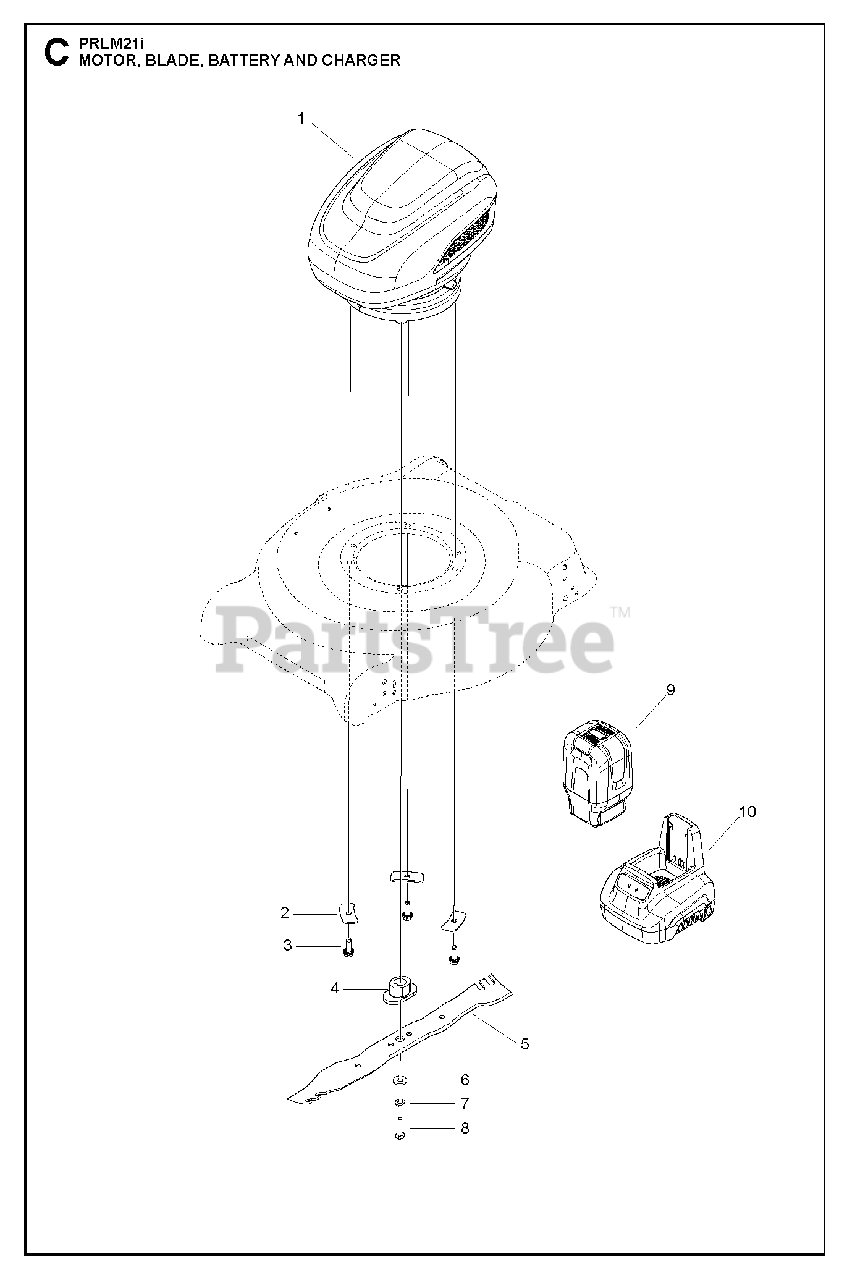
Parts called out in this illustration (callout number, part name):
1	MOTOR ASSYMotor, 58V Poulan Pro. Includes User Interface Control
3	SCREW3/8-16 x 1, Dogpoint
4	ADAPTERBlade, 25 mm
5	MOWER BLADE21", Low Lift
6	WASHERHardened
7	WASHER3/8, Helical Spring
8	BOLTHex Head Machine Screw
9	BATTERY58V, 5.2Ah, Poulan Pro
10	CHARGER58V, 230 W, Poulan Pro
